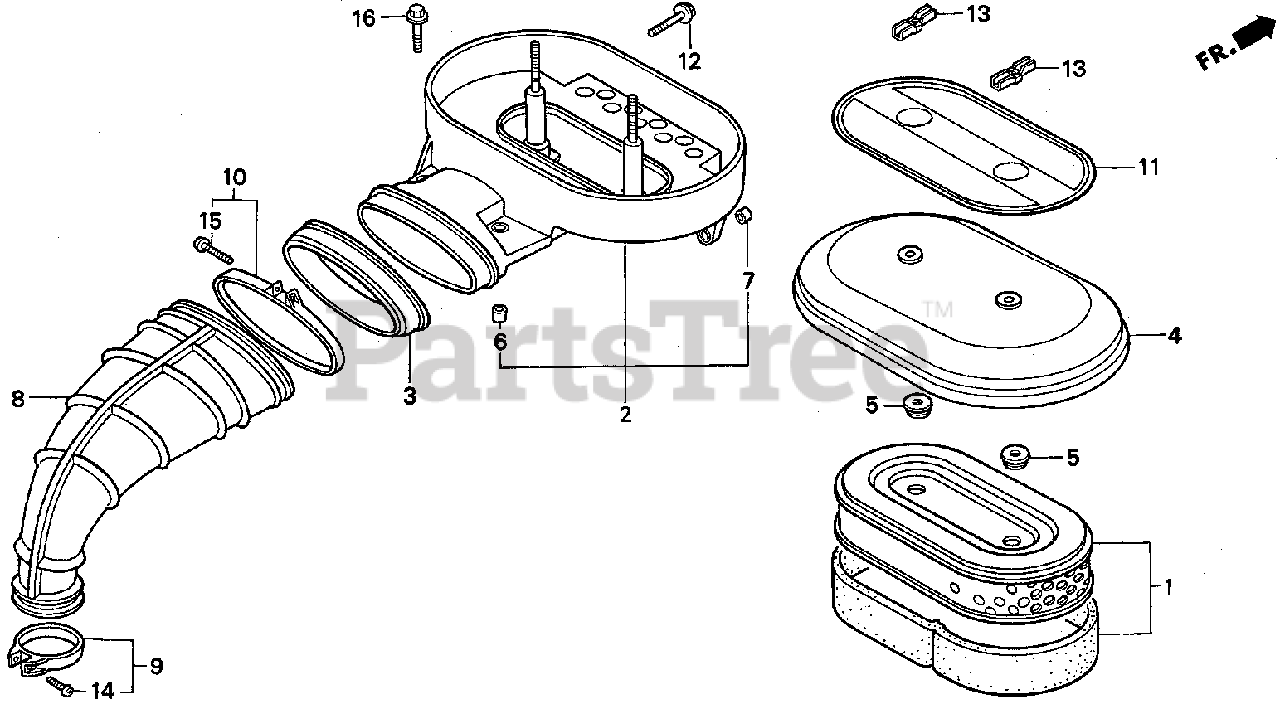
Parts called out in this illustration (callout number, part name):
1	ELEMENT, AIR CLEANER (DUAL)
2	HOUSING, AIR CLEANER
3	SUPPORTER, AIR CLEANER
4	COVER, AIR CLEANER
5	GROMMET, AIR CLEANER
6	COLLAR A, AIR CLEANER
7	COLLAR B, AIR CLEANER
8	TUBE, AIR CLEANER CONNECTING
9	BAND, CONNECTING TUBE
10	BAND ASSY., CONNECTING TUBE
11	EMBLEM
12	BOLT, FLANGE (6X25)
13	WINGNUT, AIR CLEANER COVER
14	SCREW, PAN (4X26)
15	SCREW, PAN (4X25)
16	BOLT, FLANGE (6X35)
